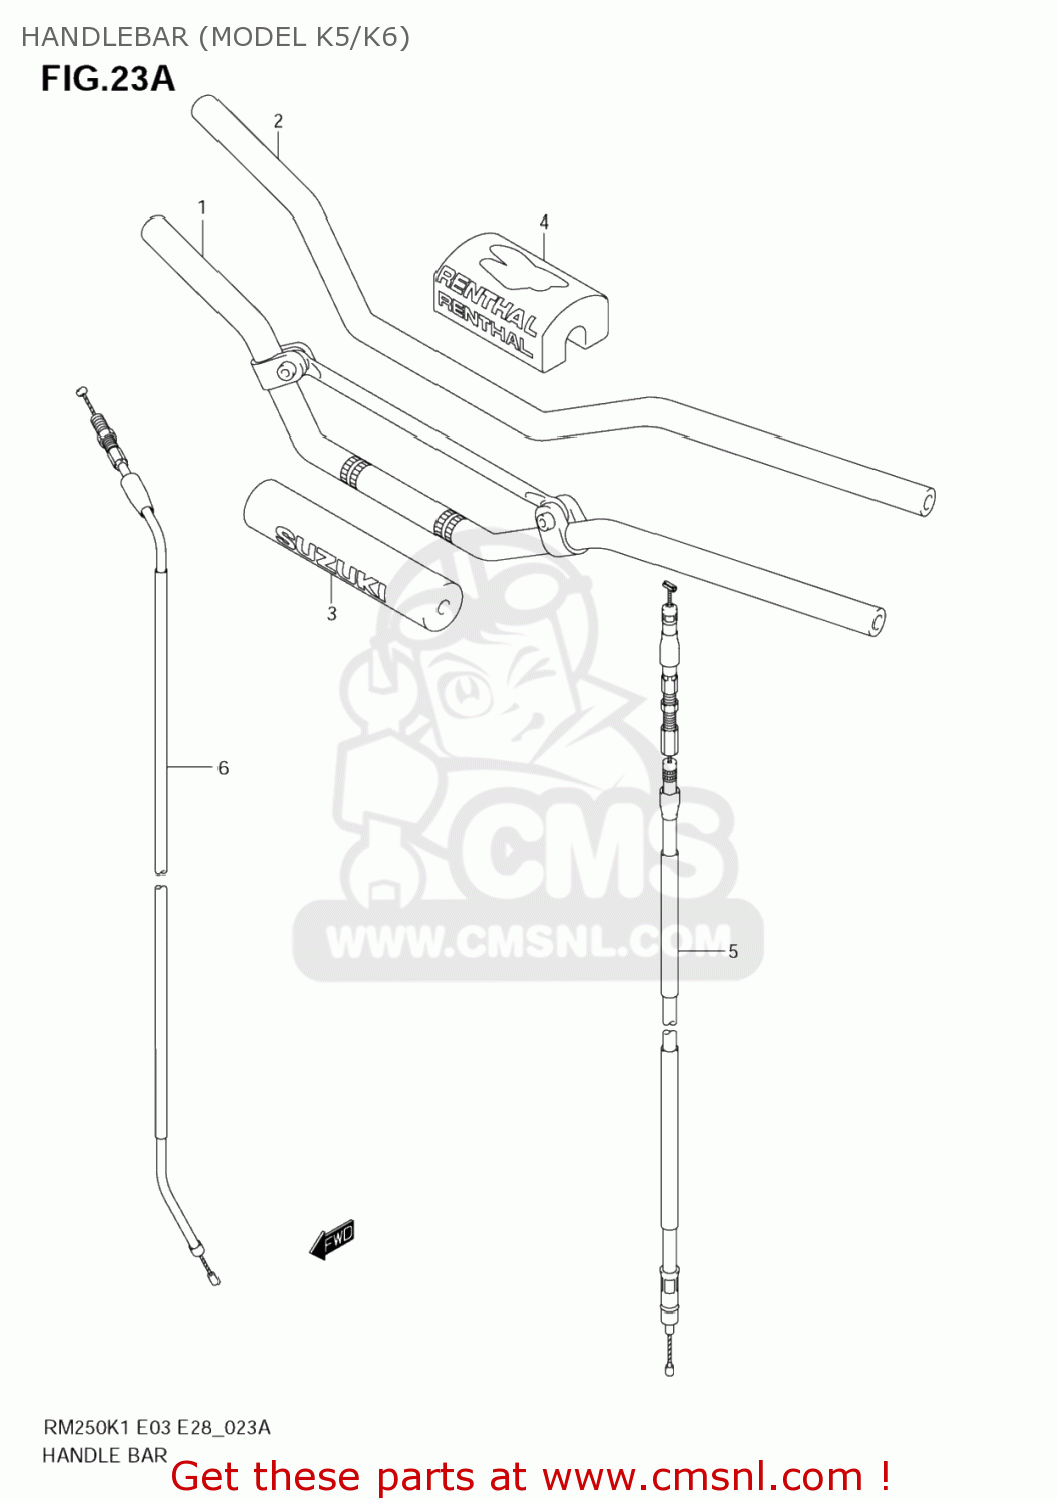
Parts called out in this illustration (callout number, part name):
1	HANDLEBAR
2	HANDLEBAR
3	PAD SET,CROSS (NAS)
4	PAD SET,HANDLEBAR (NAS)
5	CABLE ASSY,CLU
6	CABLE ASSY,THROTTLE
